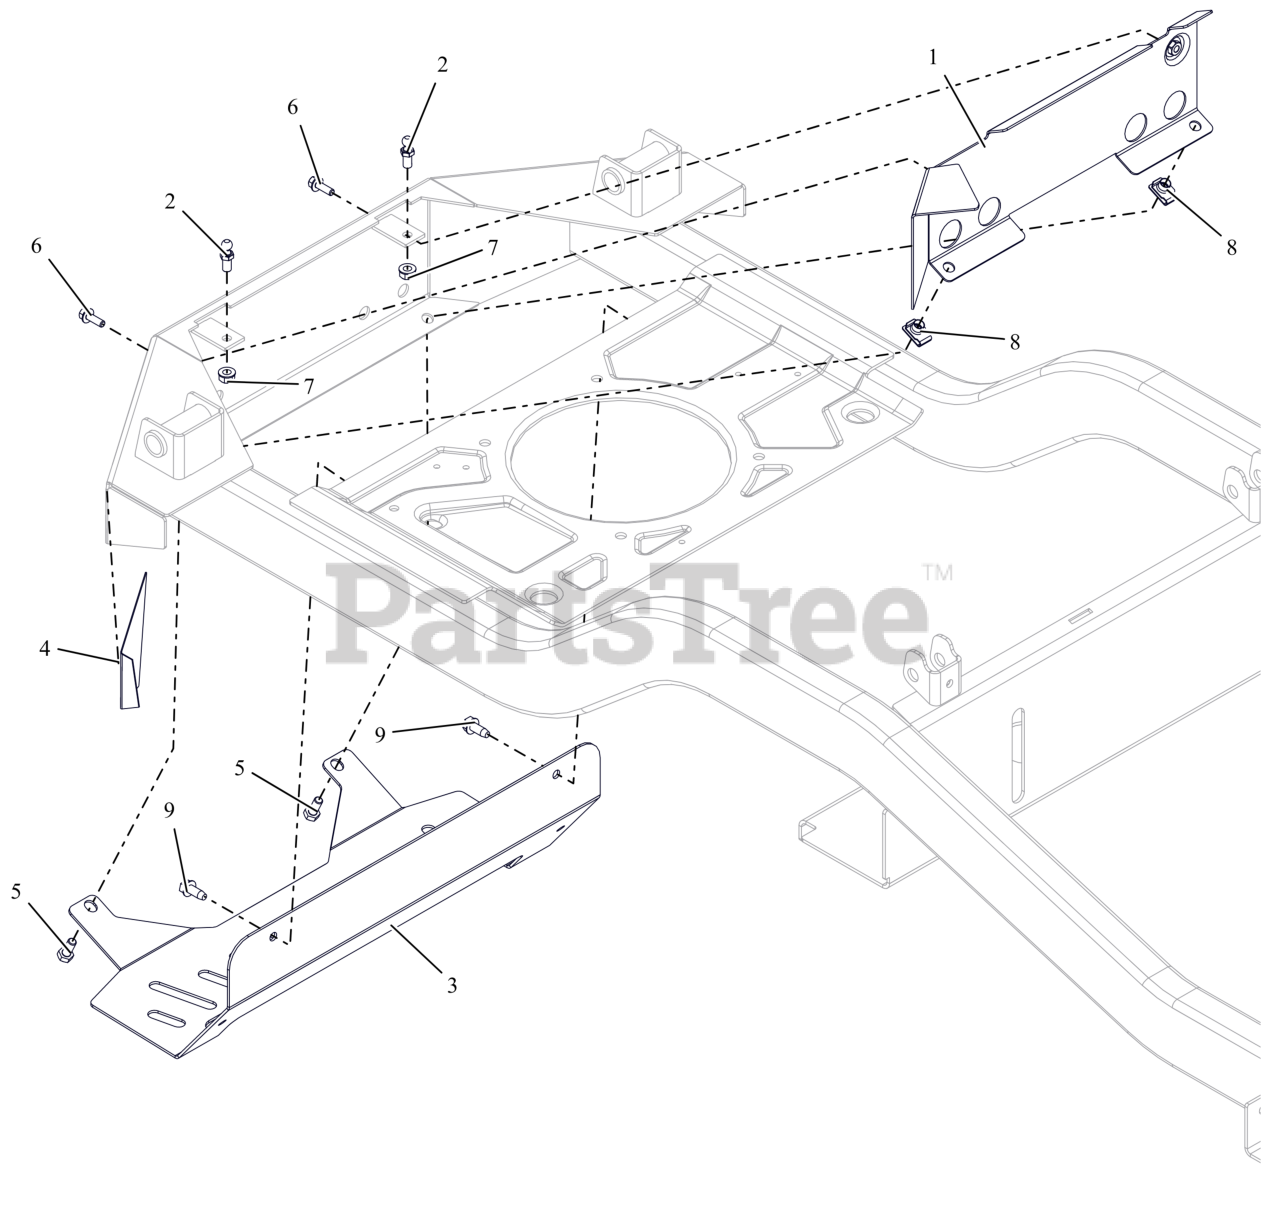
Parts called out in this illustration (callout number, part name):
1	WMT, HEAT BAFFLE
2	STUD- BALL
3	SHIELD, HEAT (HD)
4	TAPE, HEAT DEFLECTOR
5	BLT,HEX .31-18X.75 G5 ZCC
6	BLT,HEX-FLG .25-20X.75 G5 BFP
7	NUT,LK-CTR-FLG .31-18 GF ZCC
8	NUT-CLIP RETAINER 5/16-18X.56
9	SCR,TAP .312-18X.75 HWH TR ZCC
